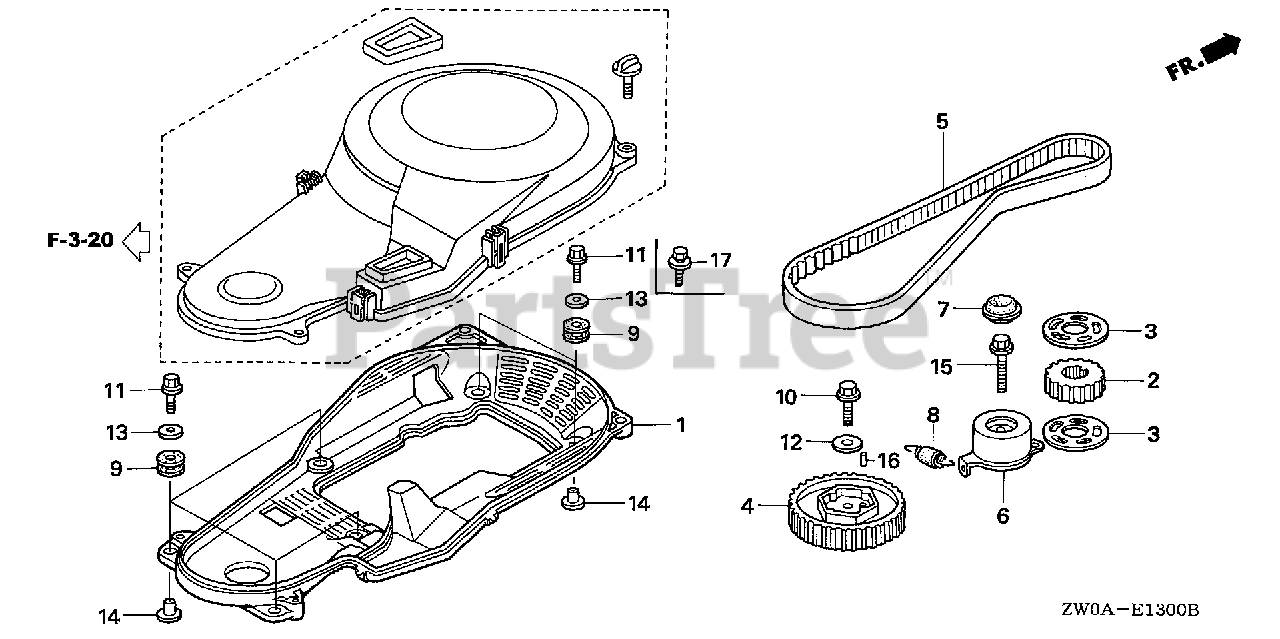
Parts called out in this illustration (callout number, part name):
1	COVER, TIMING BELT (LOWER)
2	PULLEY, TIMING BELT DRIVE
3	PLATE, TIMING BELT GUIDE
4	PULLEY, TIMING BELT DRIVEN
5	BELT, TIMING
6	TENSIONER, TIMING BELT
7	CAP, TIMING BELT TENSIONER
8	SPRING, TIMING BELT ADJUSTING
9	GROMMET, CASE (LOWER)
10	BOLT, FLANGE (10X32)
11	BOLT, FLANGE (6X25)
12	WASHER (10X28X5)
13	WASHER, PLAIN (6MM)
14	COLLAR, MODULE IGNITION CONTROL CASE (CDI)
15	BOLT, FLANGE (10X45)
16	ROLLER (4X10)
